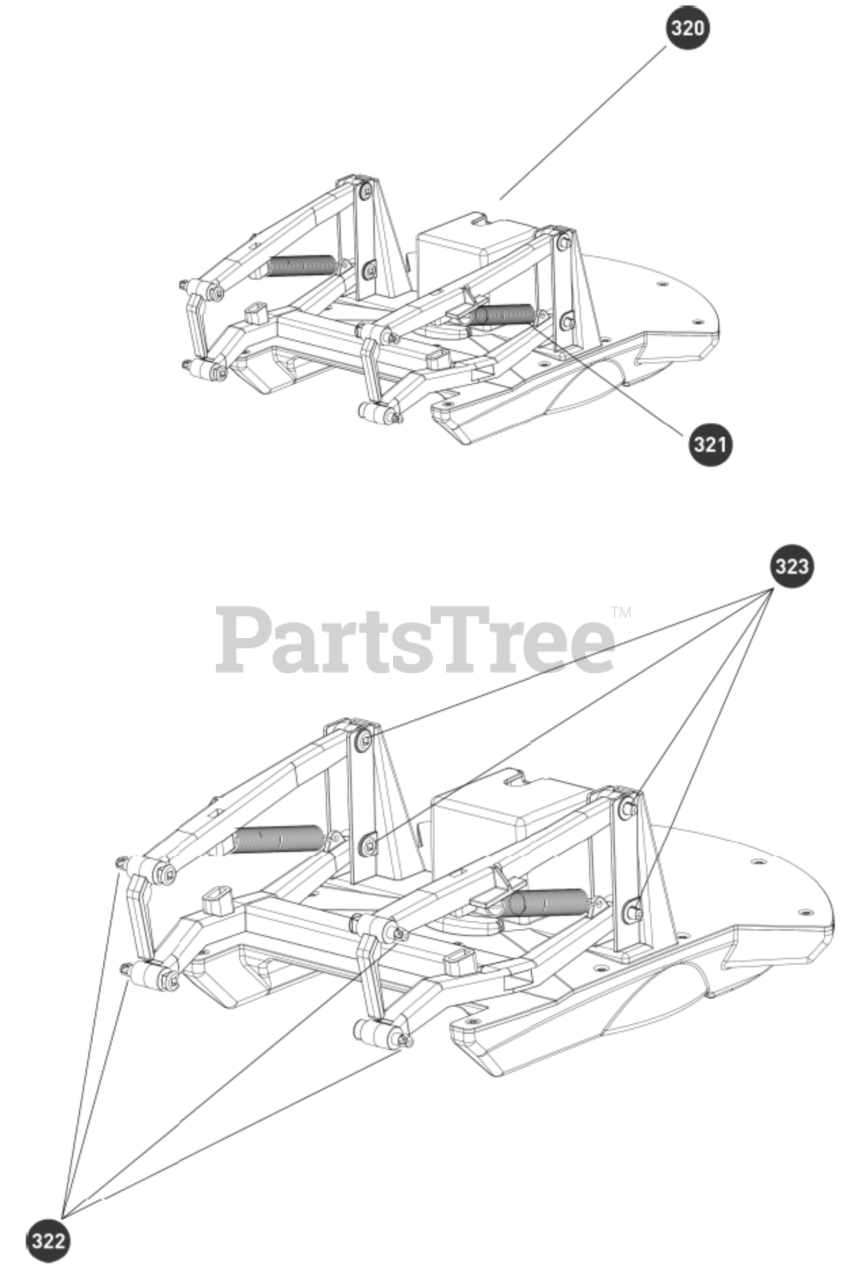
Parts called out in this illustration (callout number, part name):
320	DECK ASSEMBLY (RX)
321	MOWER DECK SPRING (RX)
322	MOWING ARM LONG PIN RX
323	MOWING ARM SHORT PIN RX
